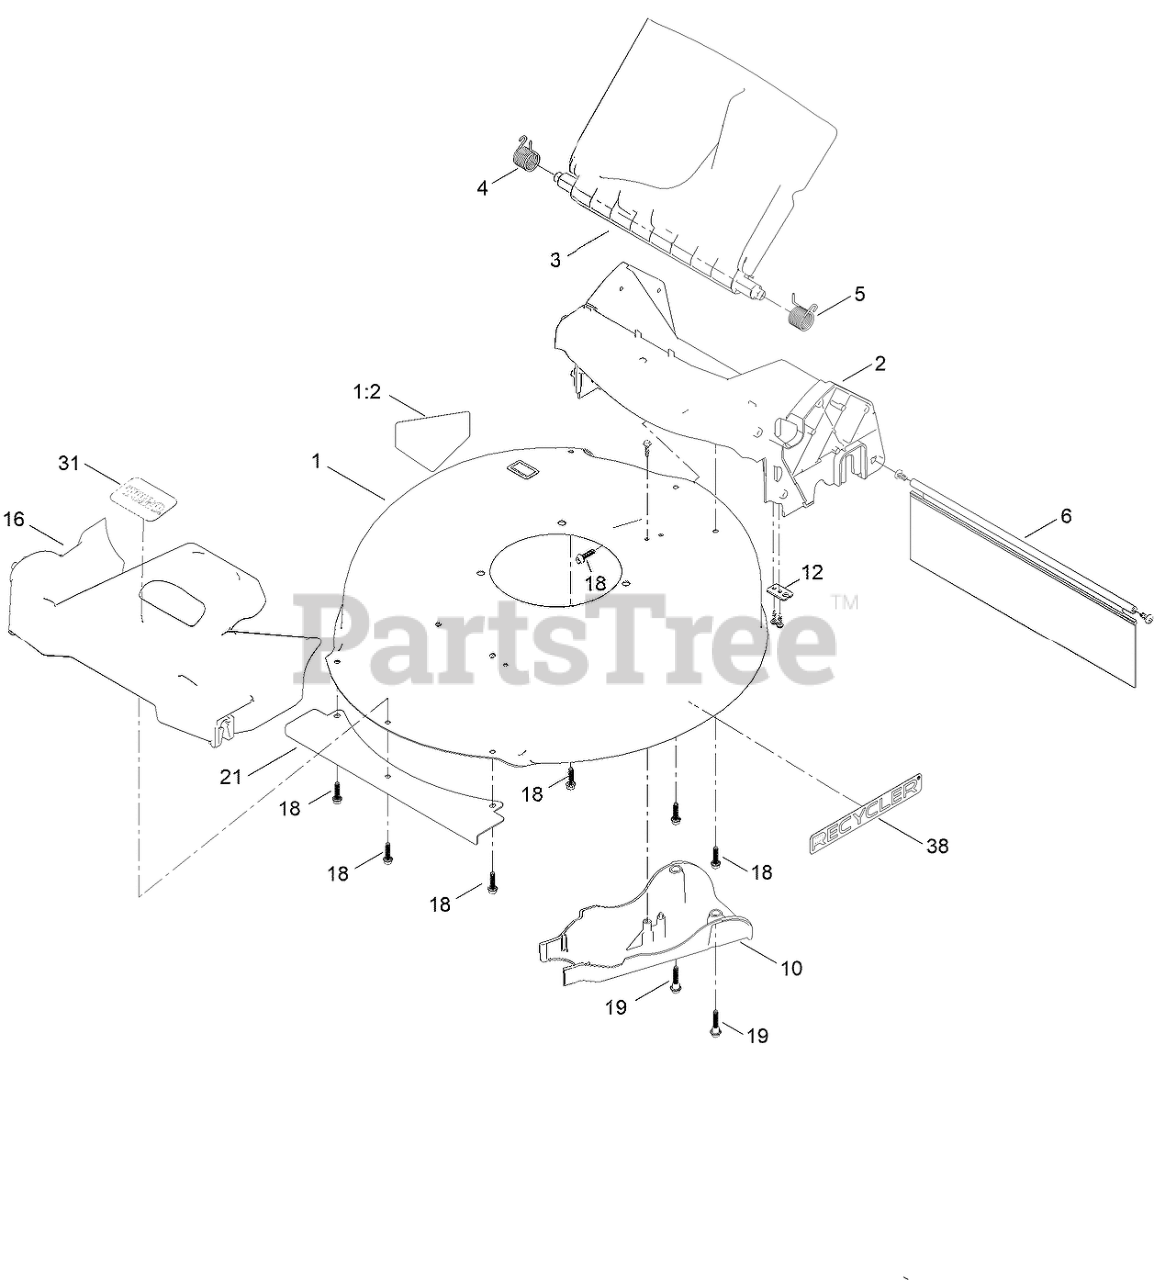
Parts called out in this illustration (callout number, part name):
1	HOUSING-DECK
1:2	DECAL-DANGER
2	CHUTE-SP/AWD, 21 IN
3	DEFLECTOR-REAR ASM
4	SPRING-TORSION
5	SPRING-TORSION
6	SHIELD-TRAILING
10	COVER-BELT
12	BRACKET-CABLE
16	BUMPER
18	SCREW-FLANGE, PLASTIC
19	SCREW-SHOULDER, HHF
21	SHIELD-FRONT
31	DECAL-TORO, SILVER
38	DECAL-eRECYCLER
